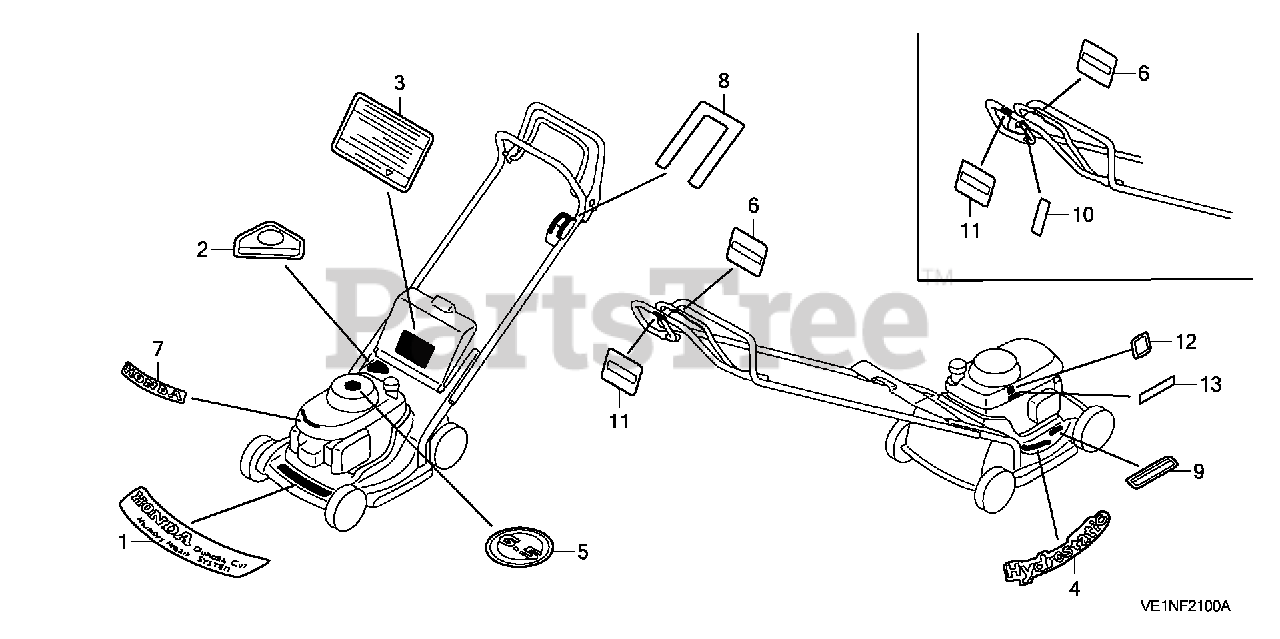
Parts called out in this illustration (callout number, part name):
1	MARK, EMBLEM (HRB217)
2	CAUTION C, HOUSING
3	LABEL, WARNING (ENGLISH)
4	MARK (H.S.T.)
5	MARK, RECOIL COVER (NA USE ALT:87169-VH7-B01)
6	MARK, CLUTCH INDICATION (ENGLISH)
7	MARK, HONDA
8	MARK, THROTTLE INDICATION (ENGLISH)
9	LABEL, HEAT WARNING
11	MARK, BLADE CONTROL (ENGLISH)
12	MARK, OIL CAUTION
13	MARK, OIL RECOMMENDED
